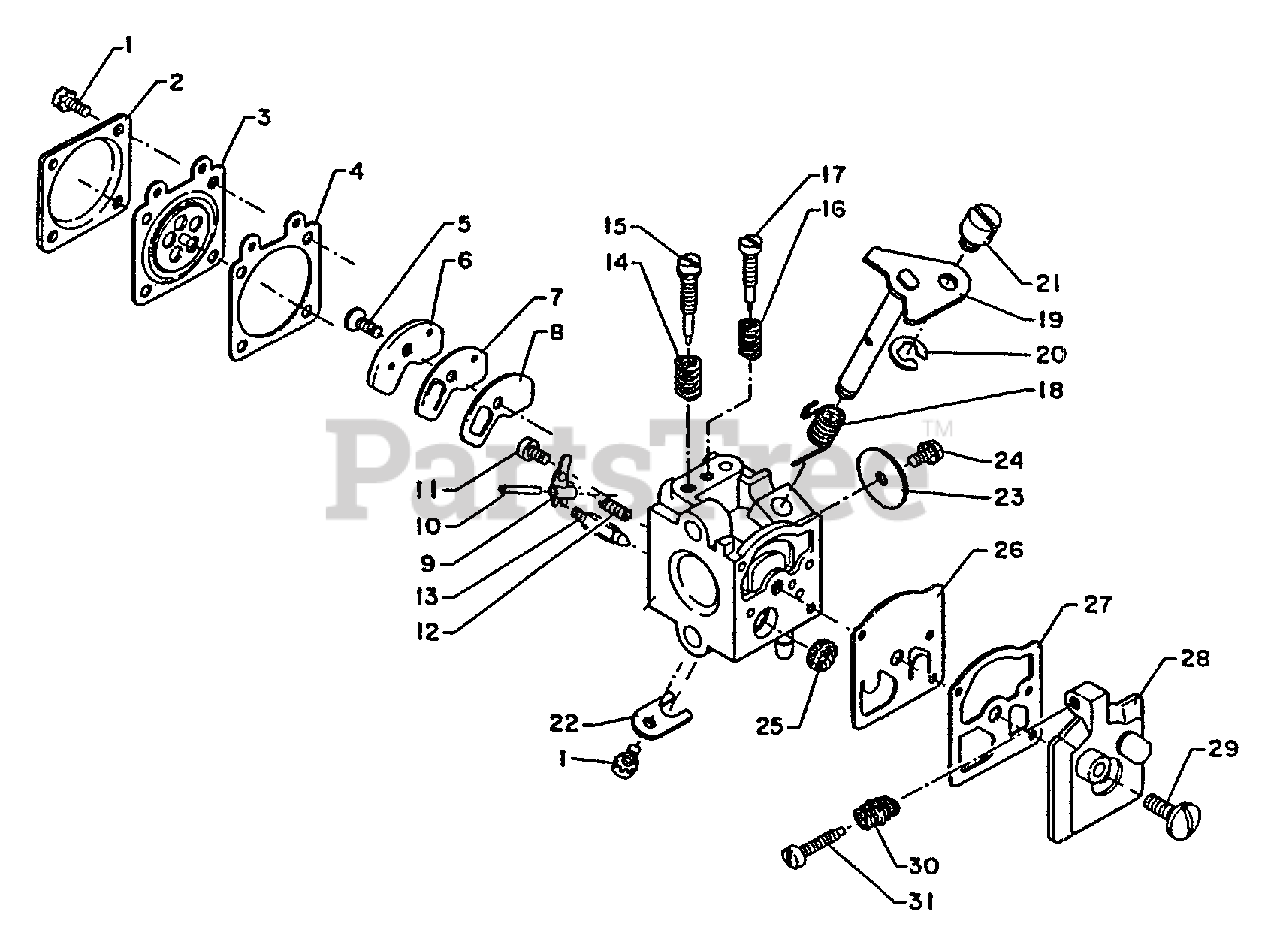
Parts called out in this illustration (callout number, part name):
1	SCREW
2	COVER, METERING DIAPHRAGM
3	DIAPHRAGM, METERING
4	GASKET, METERING
5	SCREW
6	PLATE, CIRCUIT
9	LEVER, METERING
10	PIN, METERING LEVER
11	SCREW, METERING LEVER PIN
12	SPRING, METERING LEVER
13	VALVE, INLET NEEDLE
14	SPRING
15	NEEDLE, HIGH SPEED
16	SPRING
17	NEEDLE, IDLE
18	SPRING, THROTTLE RETURN
19	SHAFT, THROTTLE
20	RING, RETAINING
22	CLIP, THROTTLE SHAFT
23	VALVE, THROTTLE
25	STRAINER
28	COVER, FUEL PUMP
30	SPRING, IDLE ADJUST
31	SCREW, IDLE ADJUST
